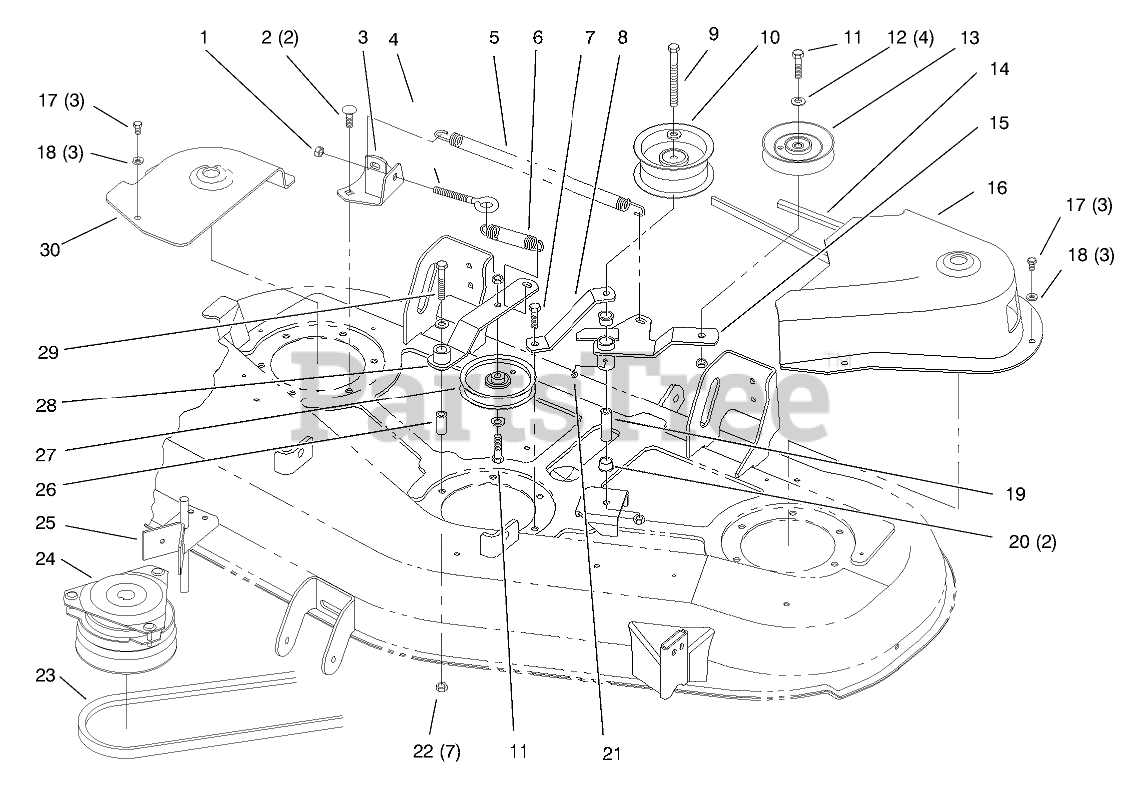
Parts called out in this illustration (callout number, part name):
1	NUT-LOCK, NI
2	SCREW-CARR
3	BRACKET-SPRING
4	BOLT-EYE
5	SPRING-EXTENSION
6	Spring-Idler
7	SCREW-HH
8	STRAP-SUPPORT
9	SCREW-HH
10	PULLEY-IDLER
11	SCREW-HH
12	WASHER-FLAT
13	PULLEY-IDLER
14	V-BELT
15	Idler Arm (Incl. Ref. #21)
16	COVER-BELT, LH
17	SCREW-HWH
18	WASHER-FLAT
19	SPACER
20	BUSHING
21	FITTING-GREASE
22	NUT-HF
23	Belt-V
24	CLUTCH - PTO
25	DECK UPSTOP ASSEMBLY
26	SLEEVE
27	Pulley
28	IDLER ARM ASM
29	SCREW-HH
30	COVER - BELT, RH
